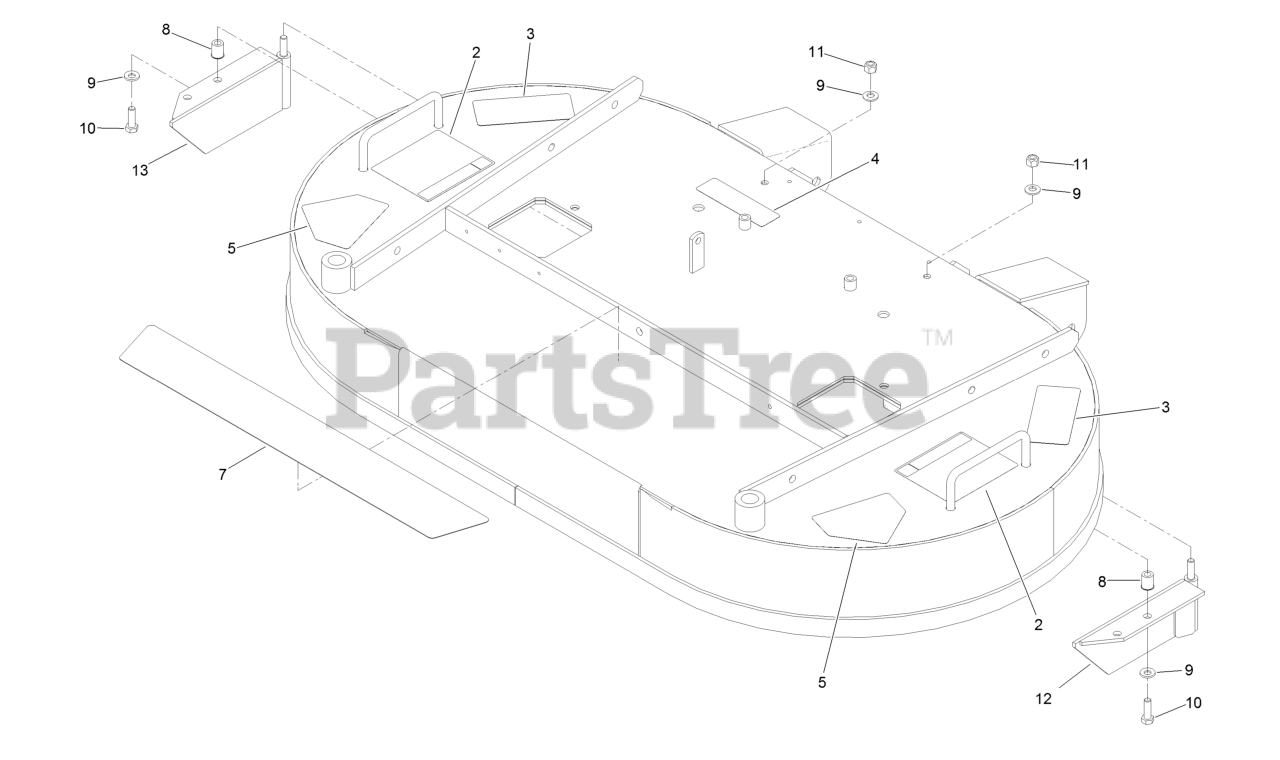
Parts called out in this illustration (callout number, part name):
2	Decal-Height Adjust, Cutting
3	Decal-Torque, Blade Bolt
4	Decal-Missing, Cover
5	Decal-Danger
7	Pad-Anti Skid
8	Nut-Insert
9	Washer-Spring
10	Screw-HH
11	Nut-Lock, NI
12	Baffle-LH
13	Baffle-RH
